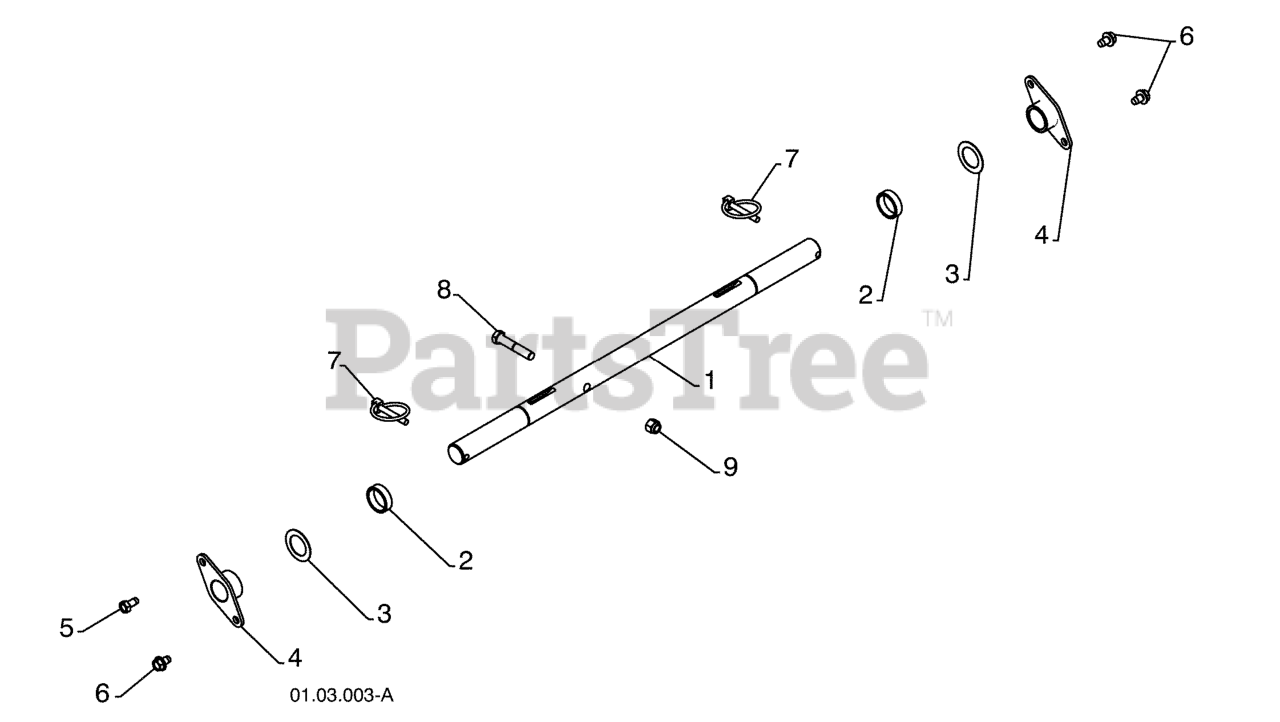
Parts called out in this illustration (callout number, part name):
1	SHAFT.AXLE.POWER.STEERING.HYD
2	SPACER.AXLE.RH
3	WASHER TRUST 1"
4	BEARING, AXLE
6	BOLT 5/16-18 X .500
7	PIN KLIK, 1/4
8	CAP.SCREW.HEX.HD.3/8-16
9	NUT
